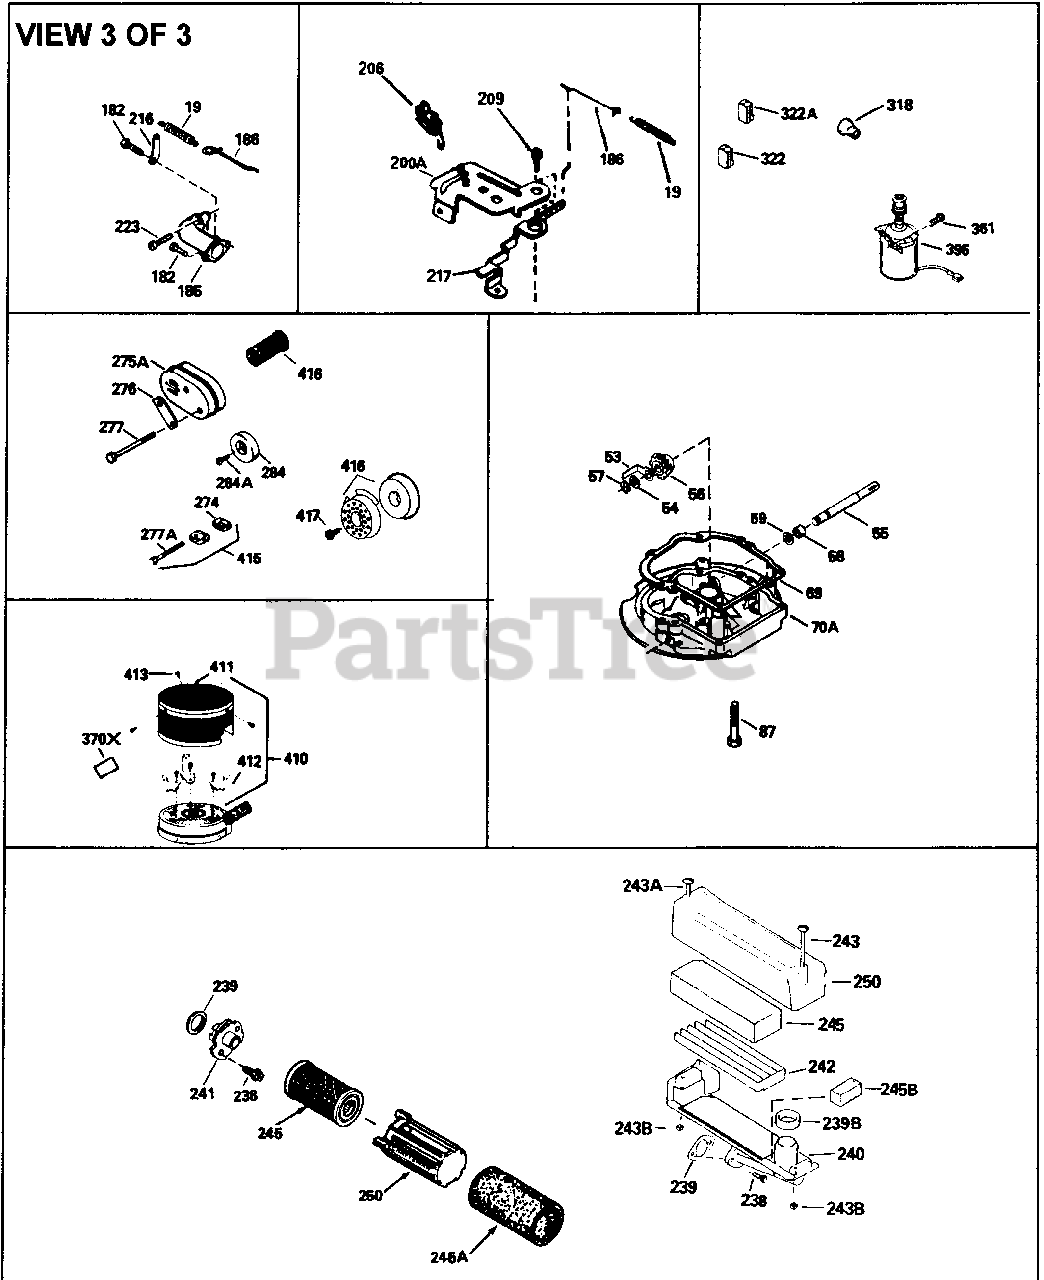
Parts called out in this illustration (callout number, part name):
19	Extension Spring
69	* Mounting Flange Gasket
182	Screw, 1/4-28 x 7/8"
185	Intake Pipe (Incl. 224)
186	Governor Link
206	Terminal
209	Screw, 10-24 x 9/16"
223	Screw, 1/4-20 x 1"
243A	Screw, 10-32 x 2-3/32"
245F	Air Filter (also available in Package d Part #740013B)
246F	Air Filter (also available in Package d Part #740013B)
247C	Air Cleaner Tube Clamp
250E	Air Cleaner Cover
260B	Blower Housing
275A	Muffler
276	Locking Plate
277	Screw, 1/4-20 x 2-1/4"
287B	Screw, 8-32 x 1/2"
300C	Fuel Tank (Incl. 299 & 301A)
322	Connector Body
390B	Rewind Starter
